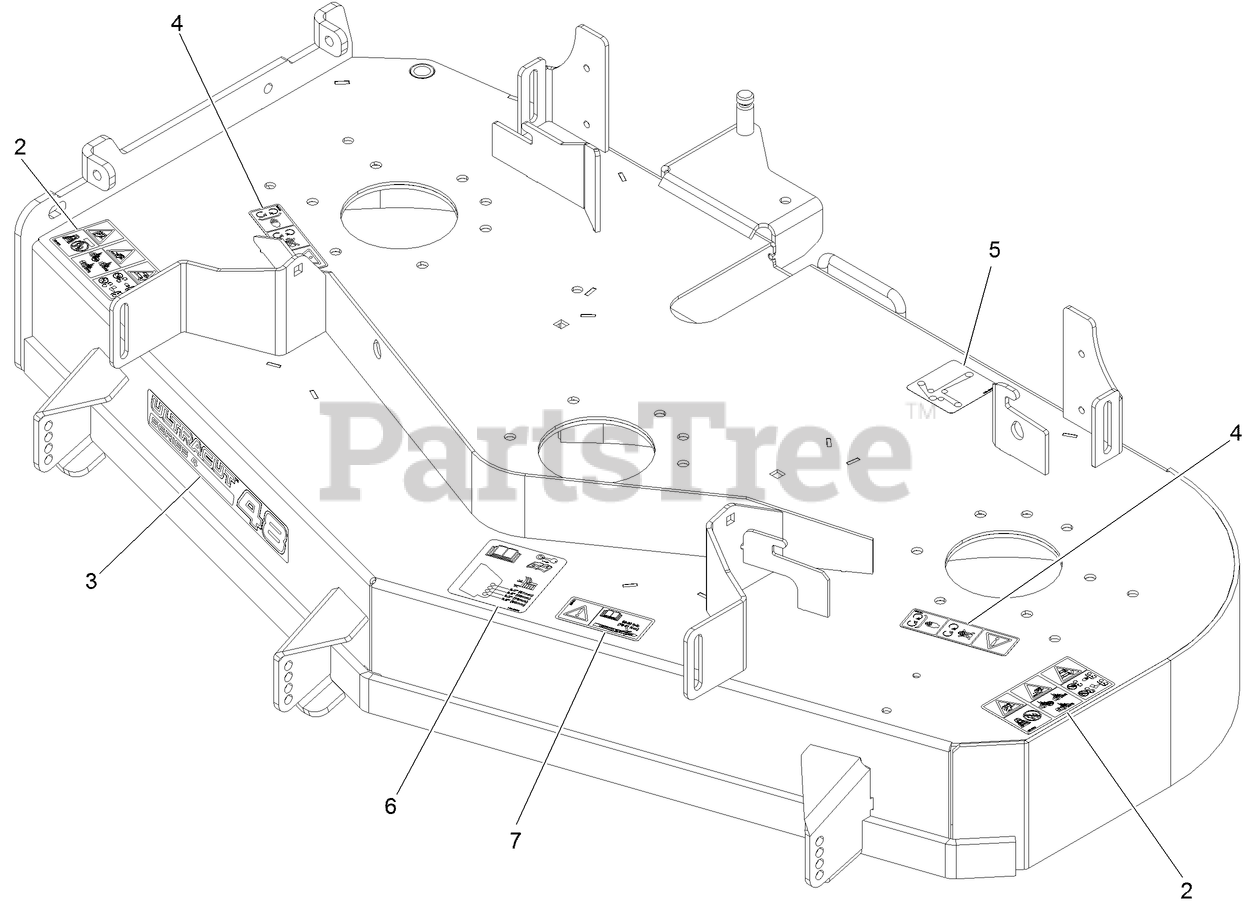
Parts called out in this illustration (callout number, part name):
2	DECAL-DANGER THROWN OBJECTS
3	DECAL, 484
4	DECAL-COVER, MISSING
5	DECAL-ROUTING, BELT
6	DECAL-ROLLER, ANTI-SCALP
7	DECAL-TORQUE, BOLT
